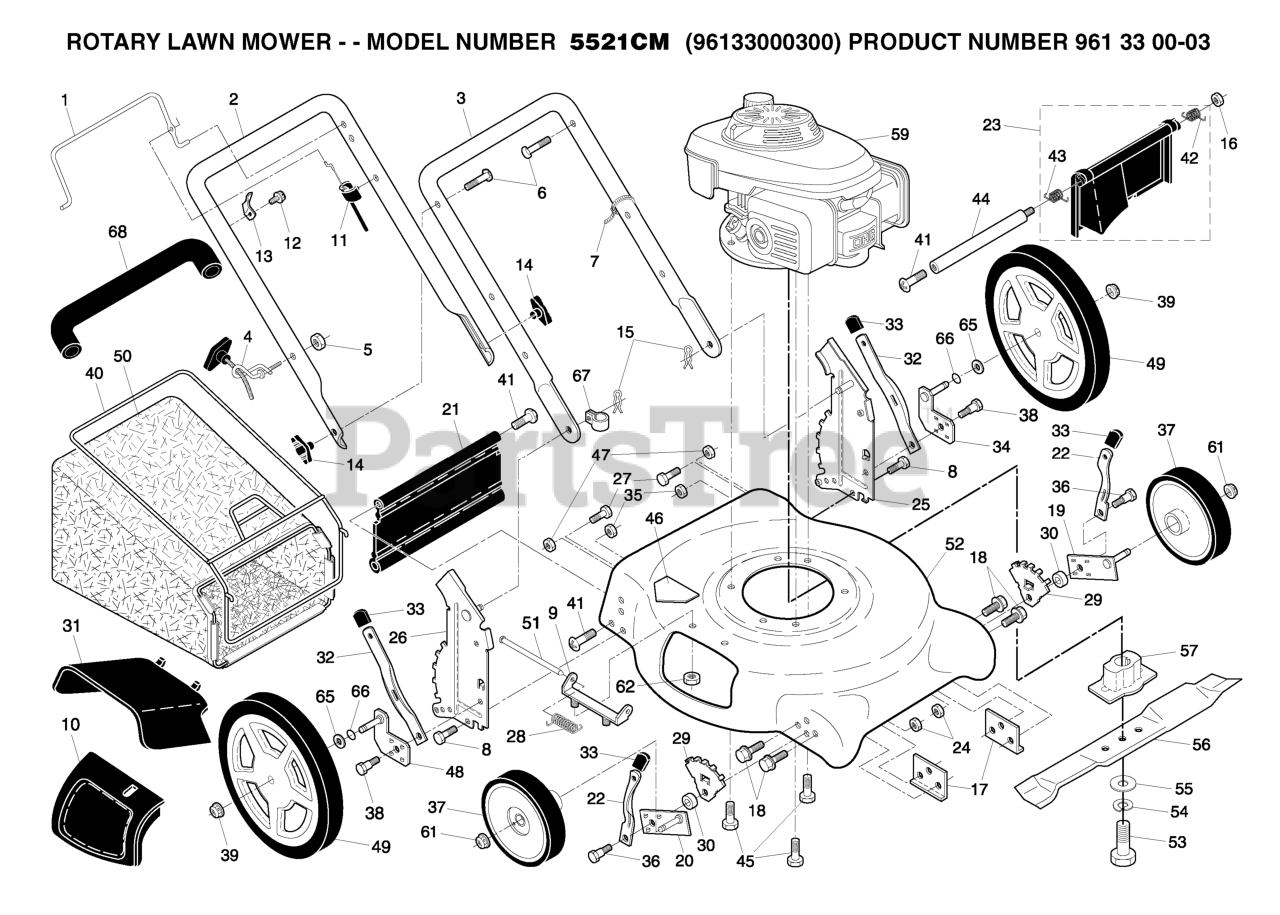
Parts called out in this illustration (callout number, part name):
1	BAIL.MZR.STD.ORANGE
2	UPPERHANDLE(INCLUDES FOAMGRIP)
3	HANDLE.LOWER.GREY
4	RB GUIDE.ROPE.STD.BLK.ZIN WSL
5	NUT
6	BOLT, HANDLE 5/16-18X1.75
7	TIE GUIDE
8	BOLT.FIN.HEX.5/16-18X3/4
9	BRACKET.ASM.HOUSING.EZ.MUL
10	RP DOOR.MULCH.21".REAR.PUSH.GR
11	ENGINE ZONE CONTROL CABLE
13	BRACKET
14	KNOB.HANDLE.STAR.HUSQ.GRAY
15	HAIRPIN COTTER
16	LOCK NUT
17	SUPPORT BRACKET
18	SCREW 1/4X20
19	AXLE ARM ASSY
20	AXLE ARM ASSY LF
21	SKIRT
22	REPL BY 532 1683-60
23	KIT.REAR.DOOR.21.DOMED.
24	NUT.CENTERLOCK.5/16-
25	BRKT.ASM.HAND.HW.21.LT
26	BRACKET.ASM.HAND.HW.21DOM.RT
27	SCREW 1/4X20
28	TORSION SPRING
29	WHEEL BRACKET ADJUSTER
30	SPACER.34X1.38X.22
31	DEFLECTOR.CLIPPING.21.GREY
32	SPRING.SEL.EXT.21.DOME
33	SELECTOR KNOB
34	ARM.ASM.AXLE.REAR.LT.B
35	LOCKNUT 5/16-18
36	SHOULDER BOLT
37	WHEEL.8X1.75.GREY.RAD3.5SPOKE
38	SHOULDER BOLT
39	NUT
40	FRAME.BAG.21.REAR.DOME
41	HINGE SCREW
42	SPRING (LH)
43	SPRING (RH)
44	ROD.STIFFENER
45	BOLT 3/8-16X1-1/8
46	DECAL HYT
47	NUT.71038.31-18.HEX.NYLOCK
48	ARM.ASM.AXLE.REAR.RT.BZP.RECS
49	WHEEL ASSY
50	GBAG.24710247.SILVER.H
51	ROD.HINGE.COMBI-C
52	HOUSING ASSEMBLY
53	SCREW, HEX HD 3/8-24 X 1-3/8
54	LOCKWASHER
55	WASHER,HARDEN
56	BLADE.21.PUSH/RWGD/FWG
57	ADAPTER.BLADE
61	HEX FLANGE LOCKNT
62	LOCKNUT.NYLOC.1/4-20
65	WASHER.FLAT.1/2
66	O-RING..070X.487.NEOPRENE
67	CLIP.CABLE.BLK
68	GRIP.HANDLE.FOAM
